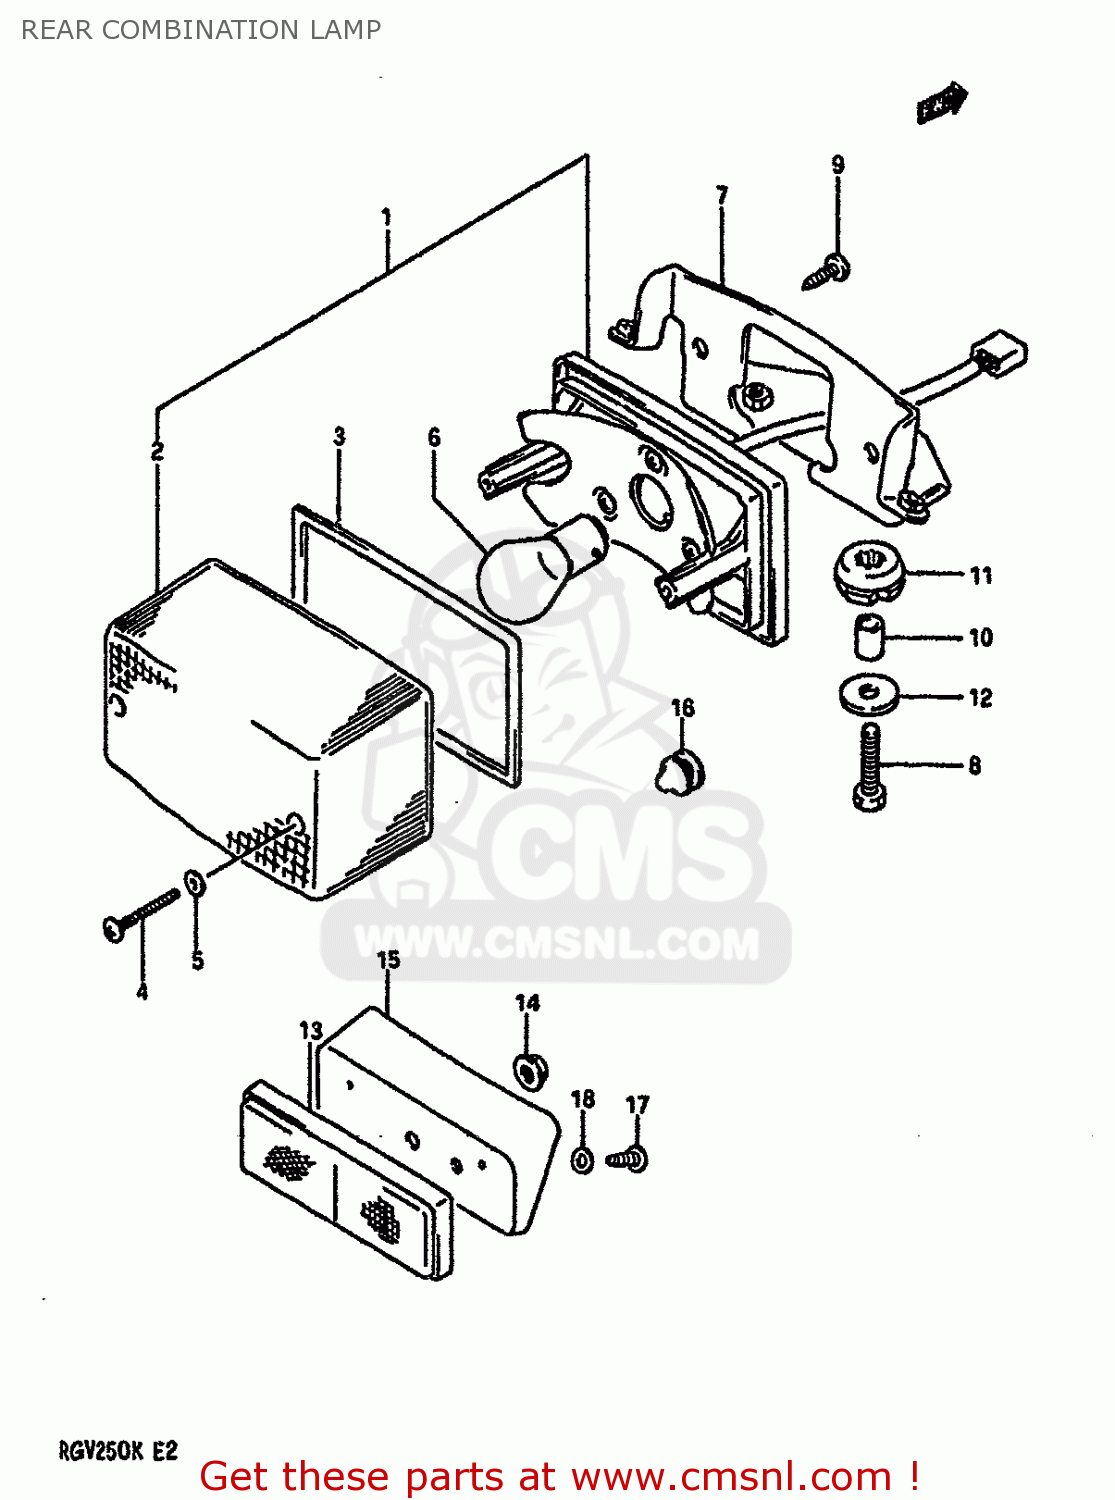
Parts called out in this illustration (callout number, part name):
1	LAMP ASSY,REAR COMBINATION
2	LENS
3	GASKET,RR COMBI LAMP LENS (NAS)
4	SCREW
5	GASKET (NAS)
6	BULB(12V21/5W)
7	BRACKET,REAR COMBINATION
8	BOLT
9	SCREW
10	SPACER (6.8X10X11.5)
11	CUSHION
12	WASHER(6.5X20X2)
13	REFLEX REFLECTOR,REAR
14	NUT
15	SPACER,RR RR
16	CUSHION
17	SCREW
18	WASHER
